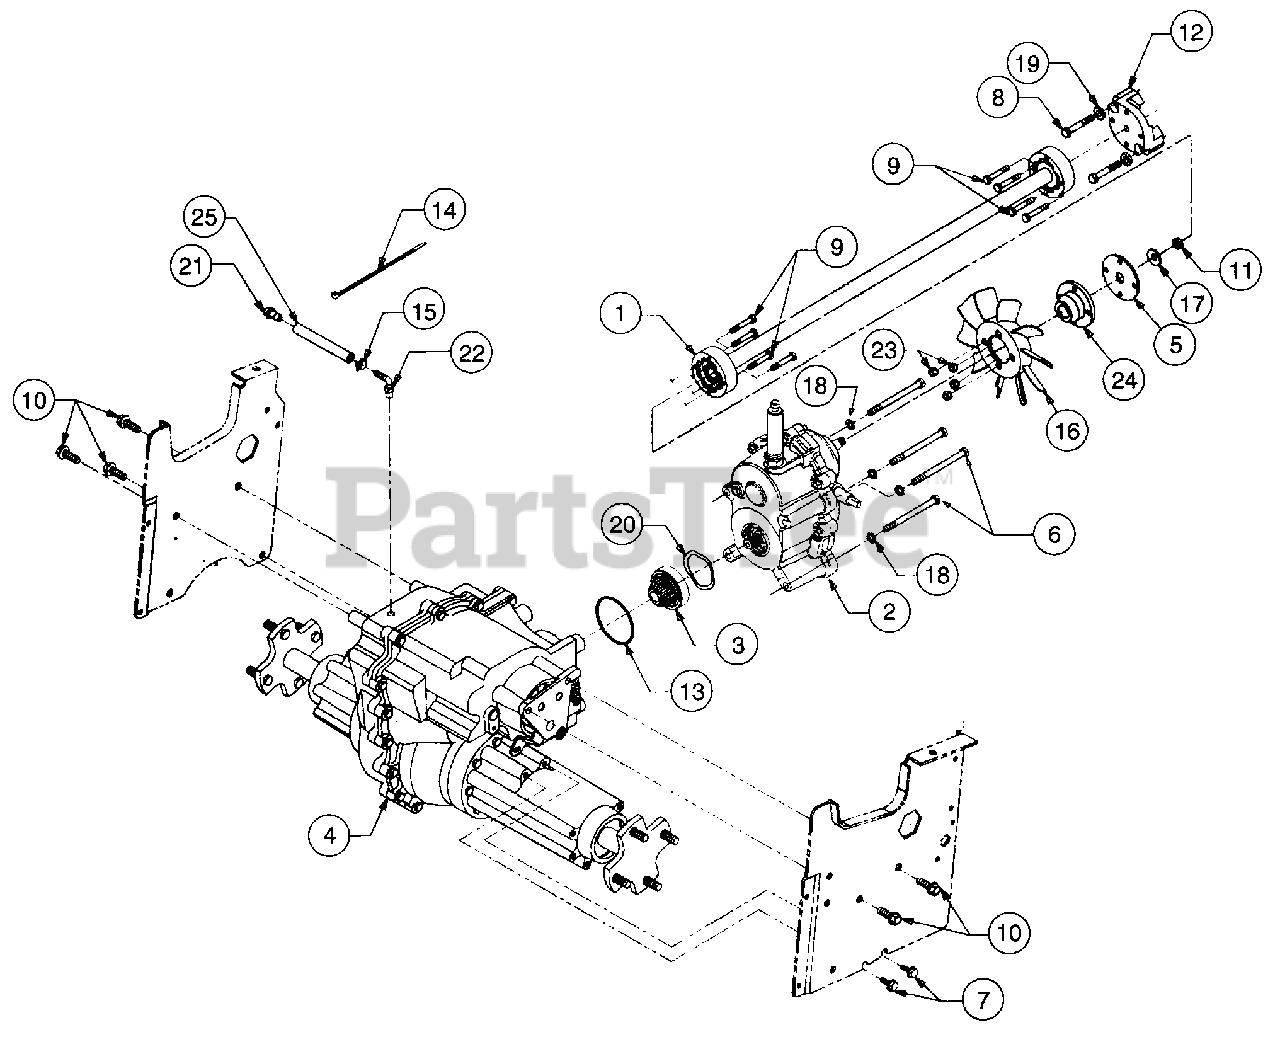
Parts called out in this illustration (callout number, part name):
1	Shaft Assy, Drive, 27.87 Lg
2	Clutch Assembly
3	Pinion Assy, Input
4	Transmission Assy, 6-Speed
5	Plate, Drive Shaft Spacer
6	Screw, Hex Cap 5/16-18 x 4.0 GR5
7	Screw, Hex Wash Hd Tapp 5/16-18 x .75
8	Screw, Hex Patch, M8-1.25 x 50mm
9	Screw, Hex Patch, 1/4-20 x 1.62 GR5
10	Screw, Hex Wash Hd Tapp 3/8-16 x 1.25
11	Nut, Hex Center Lock Jam, 3/8-24
12	Adapter, Drive Shaft
13	O-Ring, 2.75 x 1.03
14	Tie, Self-Clinch Cable
15	Clamp, Hose
16	Fan, 10 Blade Cooling
17	Washer, Bell, .380 x .88 x .063
18	Washer, Lock, 5/16
19	Washer, Flat, .312 x .750 x .119
20	Washer, Spring Wave, 1.96 x 2.44 x .06
22	Fitting, Elbow
23	Nut, Fan, 1/4-20
24	Adapter, Clutch
25	Line, Fuel, 7 in. Lg
